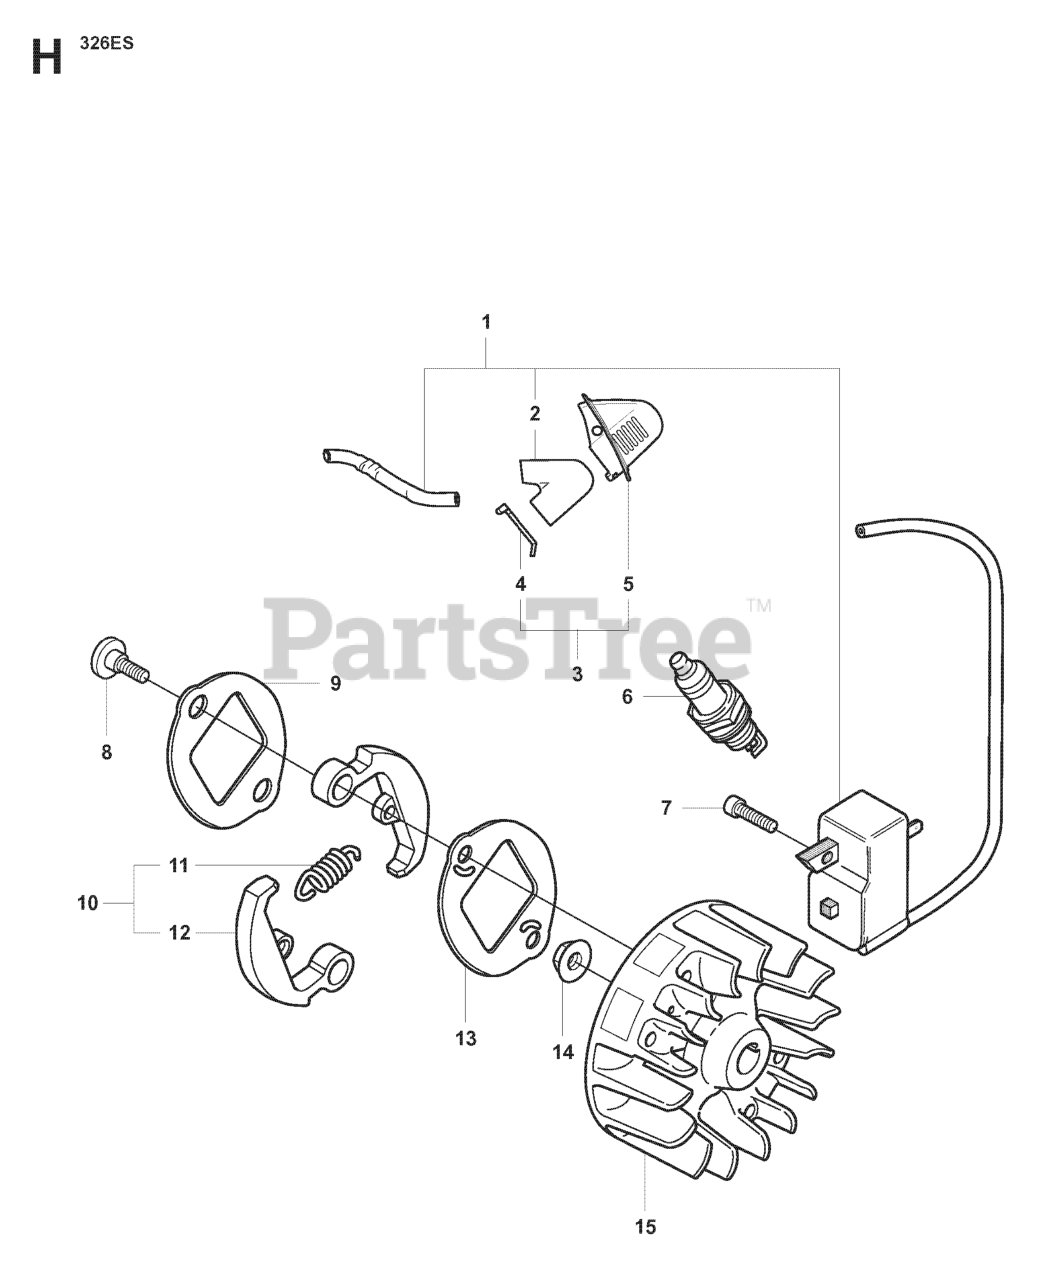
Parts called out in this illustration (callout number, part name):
1	IGNITION MODULE MB50
2	SPARK PLUG CONNECTION
6	SPARK PLUG RCJ6Y NLA
7	SCREW
9	WASHER, CLUTCH
14	FLANGE NUT
